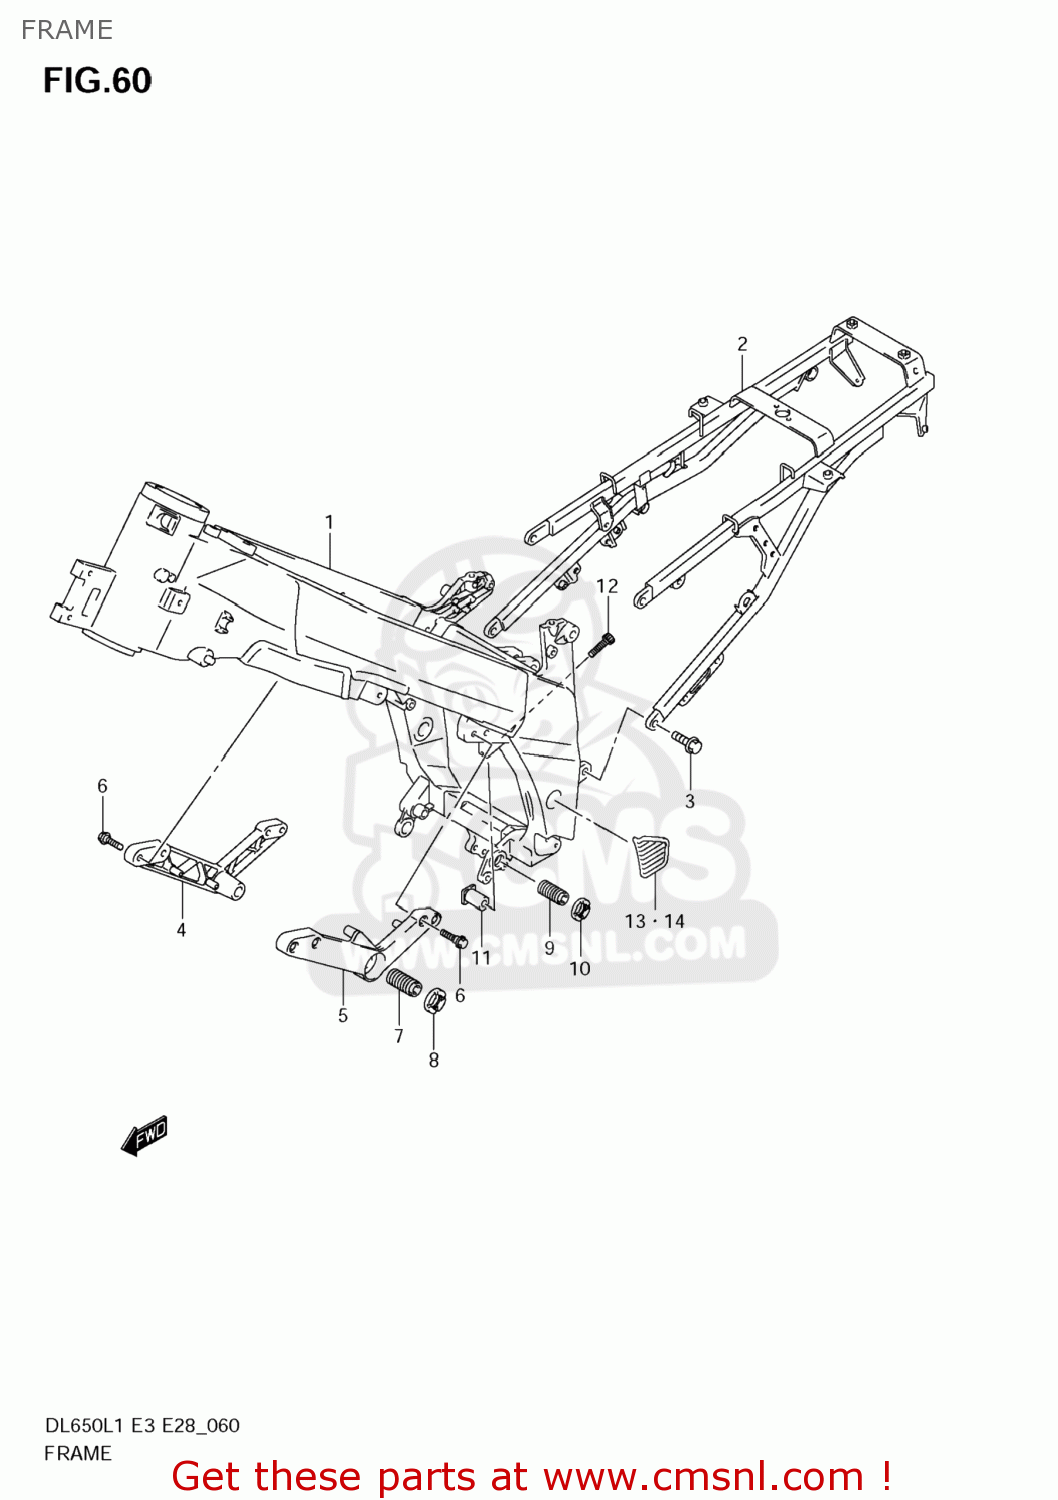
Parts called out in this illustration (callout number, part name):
1	FRAME COMP
2	RAIL,SEAT
3	BOLT(10X30)
4	BRACKET,ENGINE MOUNTING,R
5	BRACKET,ENGINE MOUNTING,L
6	BOLT(8X30)
7	BOLT,CRANK CASE ADJUST CTR
8	NUT,CRANKCASE ADJUST
9	BOLT,CASE LWR & RR HEAD ADJ
10	NUT,CRANK CASE ADJUST BOLT
11	SPACER,MOUNTING RR UPR,R
12	BOLT(8X38)
13	COVER,PIVOT,R
14	COVER,PIVOT,L
